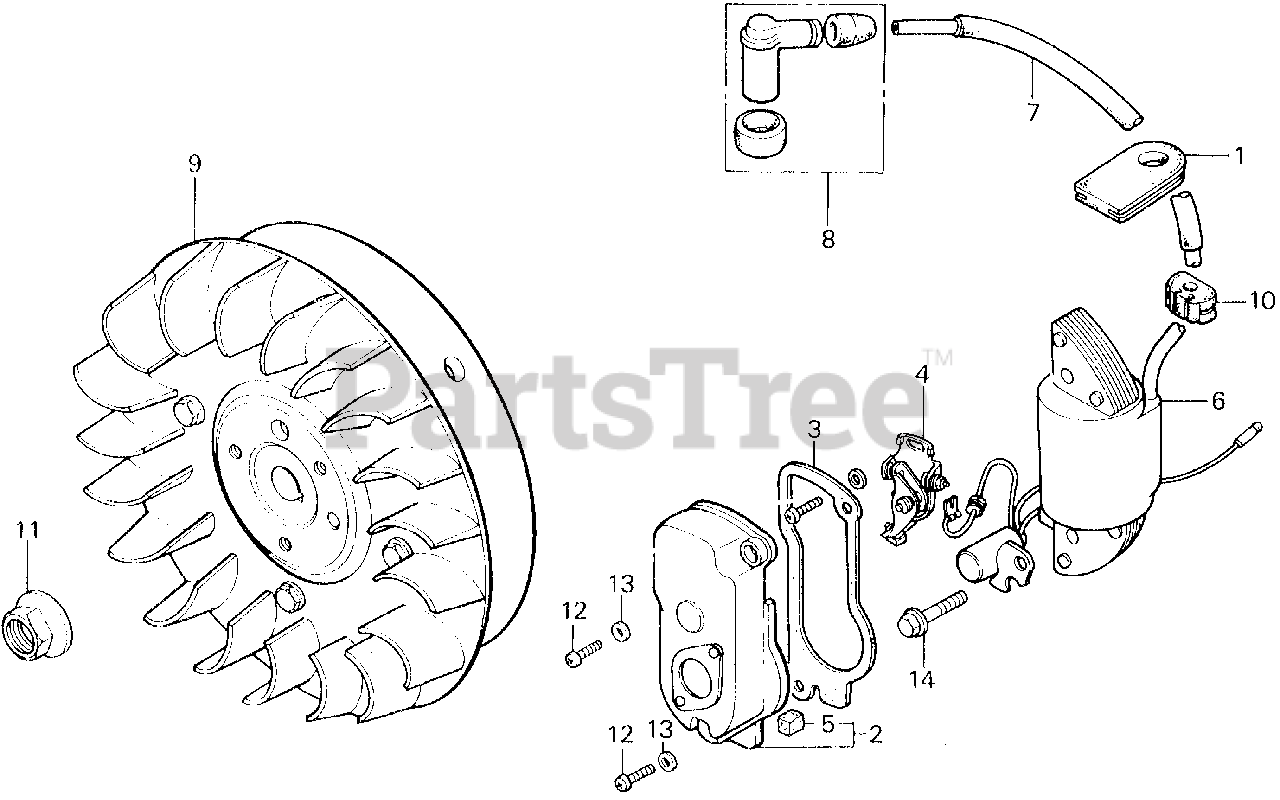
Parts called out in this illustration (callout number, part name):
1	GROMMET, WIRE
2	COVER ASSY., POINTS (NOT AVAILABLE)
2	COVER, POINTS
3	GASKET, POINT COVER (NOT AVAILABLE)
4	POINTS ASSY.
6	IGNITION ASSY.
6	COIL ASSY., IGNITION (DENSO) (NOT AVAILABLE)
7	TUBE, IGNITION RUBBER
8	CAP ASSY., NOISE SUPPRESSOR
9	FLYWHEEL ASSY.
10	GROMMET, WIRE
11	NUT, SPECIAL (14MM)
12	SCREW, PAN (4X8)
13	WASHER, PLAIN (4MM)
14	BOLT, FLANGE (6X25) (NOT AVAILABLE)
